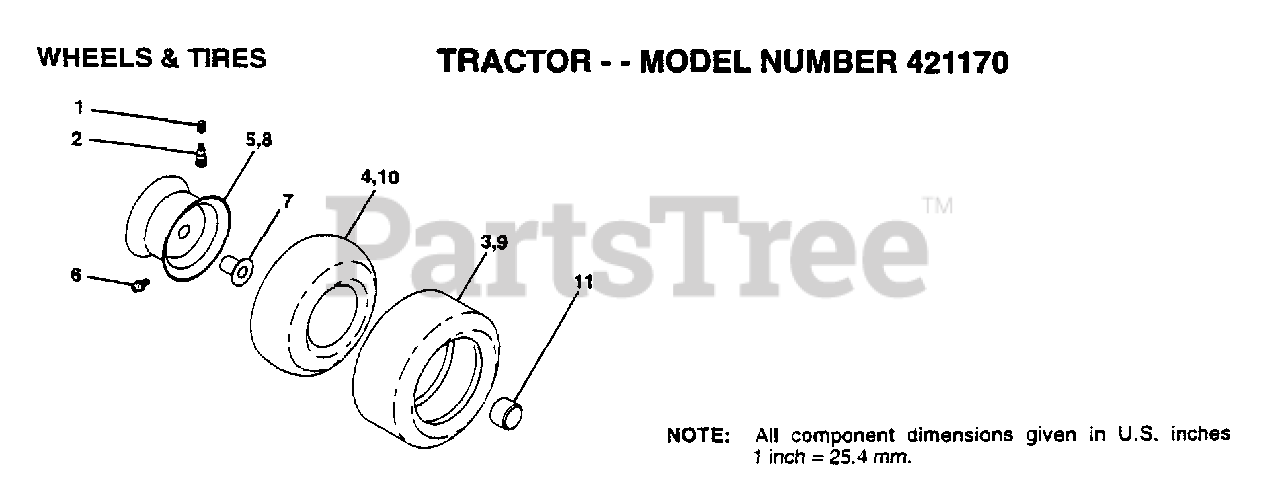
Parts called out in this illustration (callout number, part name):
1	VALVE CAP
2	VALVE STEM LT
4	TUBE.5.3/4.5/6
5	"RIM,FRT T"
6	FITTING LT
7	"FLANGE, BEARING"
8	"RIM 8"""
10	TUBE.18X9.5-8
11	HUB CAP
